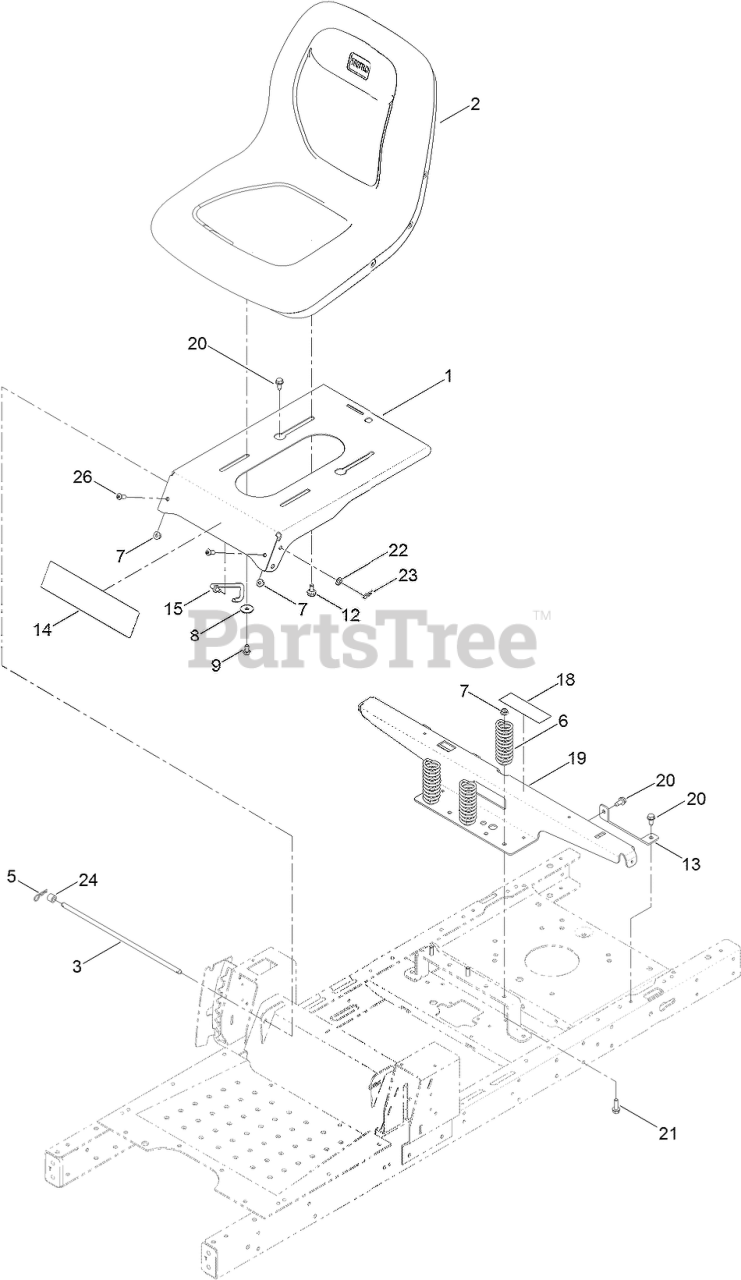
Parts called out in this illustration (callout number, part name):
1	PAN-SEAT
2	SEAT-18 INCH
3	ROD-STOP
5	PIN-COTTER
6	SPRING-COMPRESSION
7	NUT-HF, NI
8	WASHER-PIVOT
9	SCREW-HH
12	BOLT-SHOULDER
13	SUPPORT-TANK, REAR
14	DECAL-TIMECUTTER
15	STOP-SEAT
18	DECAL-SERVICE, CE
19	SUPPORT-POD, WIDE
20	SCREW-HWHTF
21	SCREW-HHF
22	WASHER-PLAIN
23	PIN-COTTER
24	BUSHING-LEVER, LIFT
26	SCREW-HSBH
